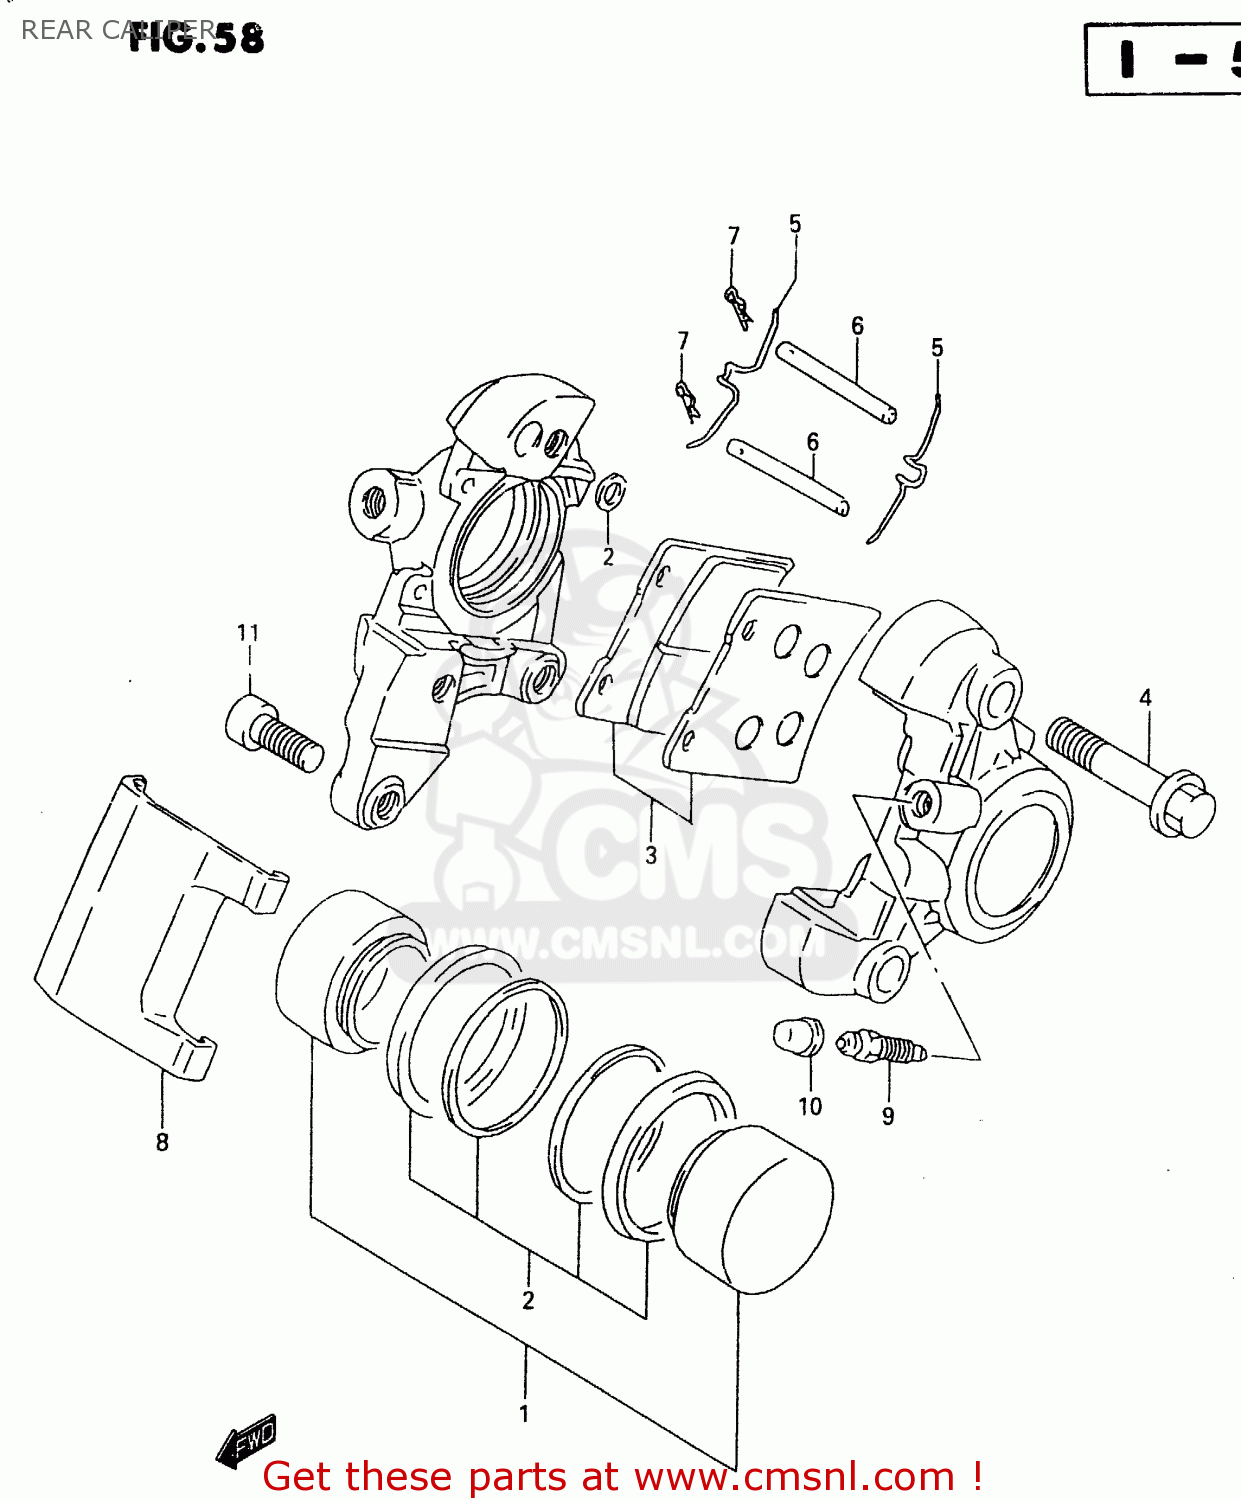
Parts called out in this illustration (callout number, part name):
1	PISTON SET
2	SEAL SET,PISTON
3	PAD SET
4	BOLT,HOUSING
5	SPRING
6	PIN,PAD
7	CLIP,PAD PIN
8	COVER
9	BLEEDER
10	CAP,BLEEDER PLUG
11	BOLT
